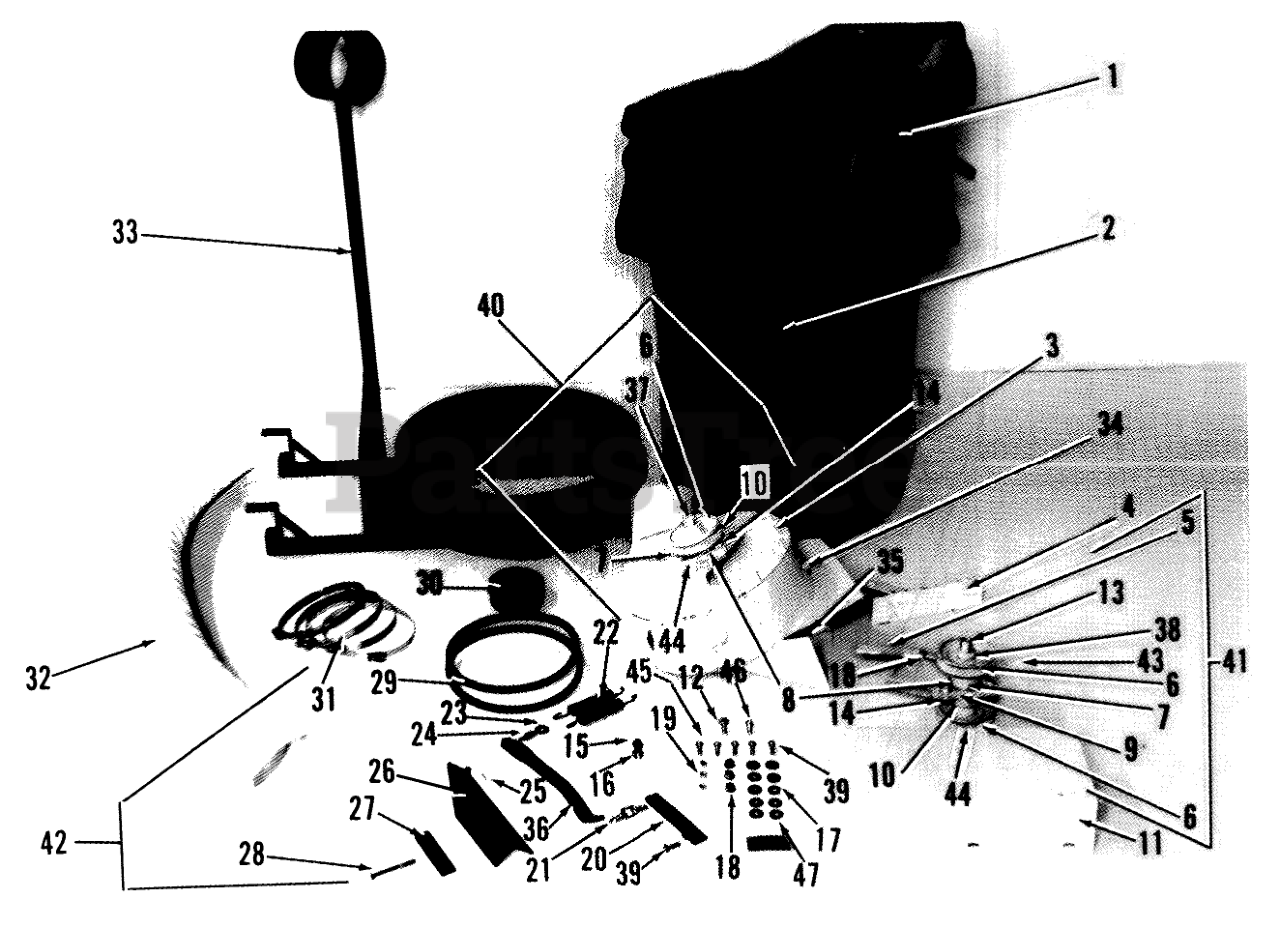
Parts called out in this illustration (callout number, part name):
1	Collector Cover
2	Collector
3	Blower Top
4	Blower Inlet Deflector
5	Strap
6	PULLEY
7	Spacer
8	Drive Hub
9	Drive Bracket
10	Bearing
11	Belt Cover
12	Bolt
13	Bolt 3/4-16 x 6
14	BOLT
15	Bolt
16	Eslok Nut
17	Washer
18	NUT
19	Nut 5/16-18 Ser F1
20	Stabilizer Adjustment Bracket
21	Chain
22	SPRING TENSION
23	Eye Bolt
24	Nut
25	HAIRPIN
26	Pivot Bracket
27	Pivot Bracket Support Bar
28	Hex Bolt 3/8-16 x 3
29	BELT-BLOWER DRIVE
30	Sheave-2 Groove
31	Hose Clamps
32	Discharge Tube
33	Collector Barrel Mounting Bracket 5.5 Bu Only
34	Blower Welded Bottom
35	IMPELLER BLOWER
36	Pivot Arm
37	BOLT HEX 3/4-16X61/2
38	Nut
39	Bolt
40	Blower-Complete
41	Blower Dbl. Pulley Drive-Complete
42	Loose Parts Package
43	SPACER
44	Zerk
45	Carriage Bolt 5/16-18 x 1/2
46	Clevis Pin 3/8 x 1 1/2
47	WASHER
